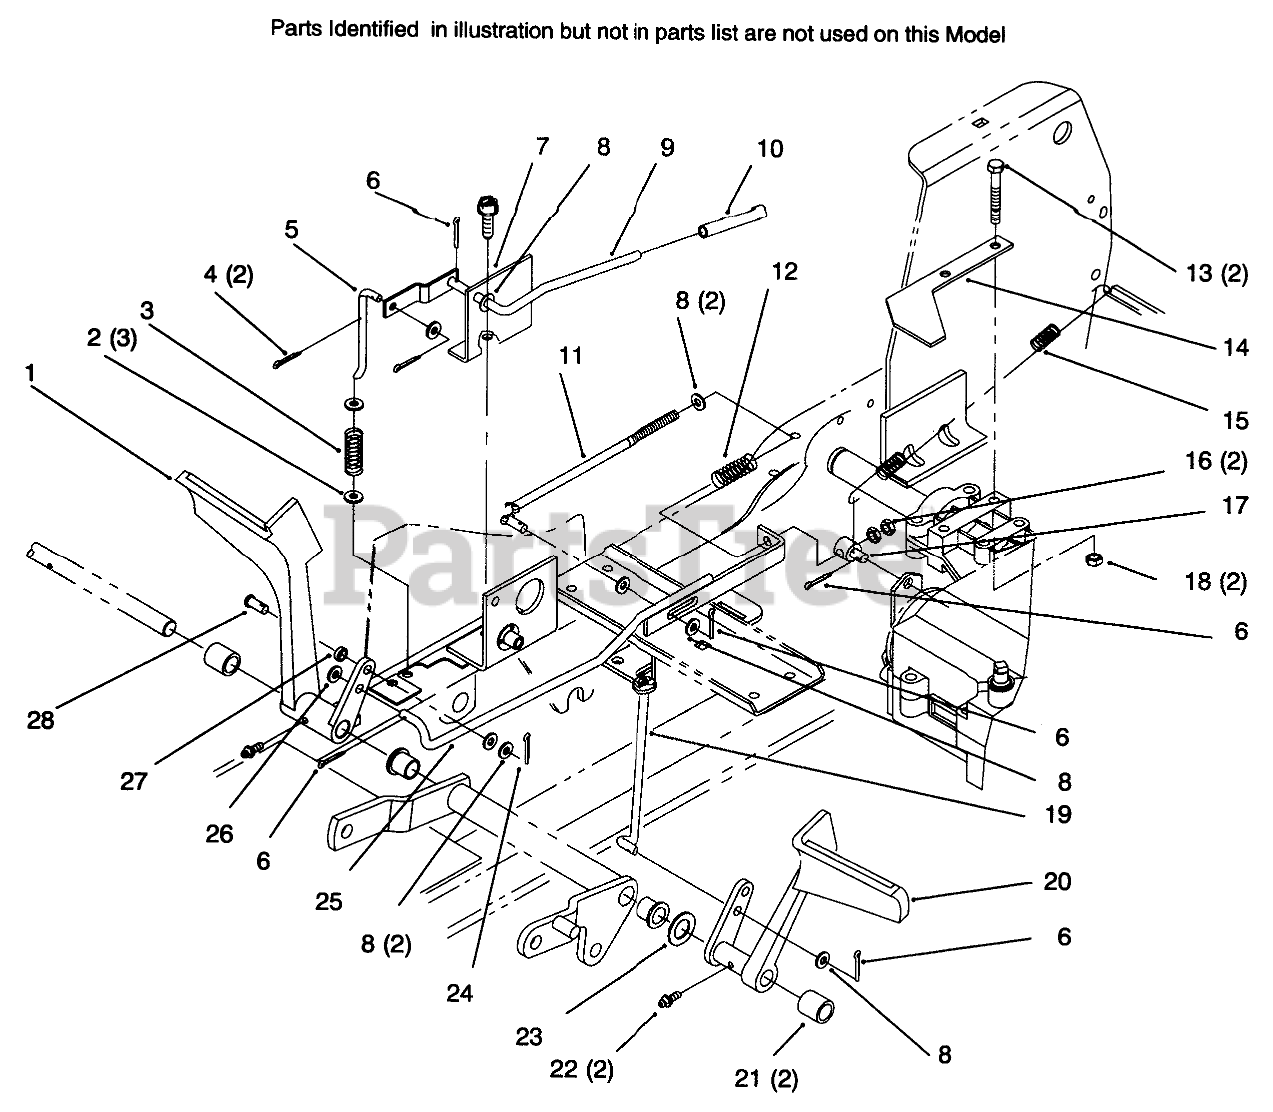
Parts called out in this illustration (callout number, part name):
1	Pedal-Brake
2	WASHER-FLAT
3	SPRING - COMPRESSION
4	PIN-COTTER
5	ROD - PARKING BRAKE
6	PIN-COTTER
7	BRKT-PARKING BRAKE
8	WASHER-PLAIN
9	PARK BRAKE LVR WAB
10	GRIP - PARKING BRAKE
11	ROD - SPRING
12	SPRING - COMPRESSION
13	SCREW-HH
14	STOP - BRAKE
15	SPRING - EXTENSION
16	NUT-JAM
17	TRUNION
18	NUT-LOCK, NI
19	CLUTCH ROD WA
20	PEDAL-CLUTCH
21	SPACER
22	FITTING-GREASE
23	WASHER-WAVE
24	PIN-COTTER
25	Brake Arm
26	WASHER-FLAT
27	BUSHING BLACK
28	PIN-CLEVIS
